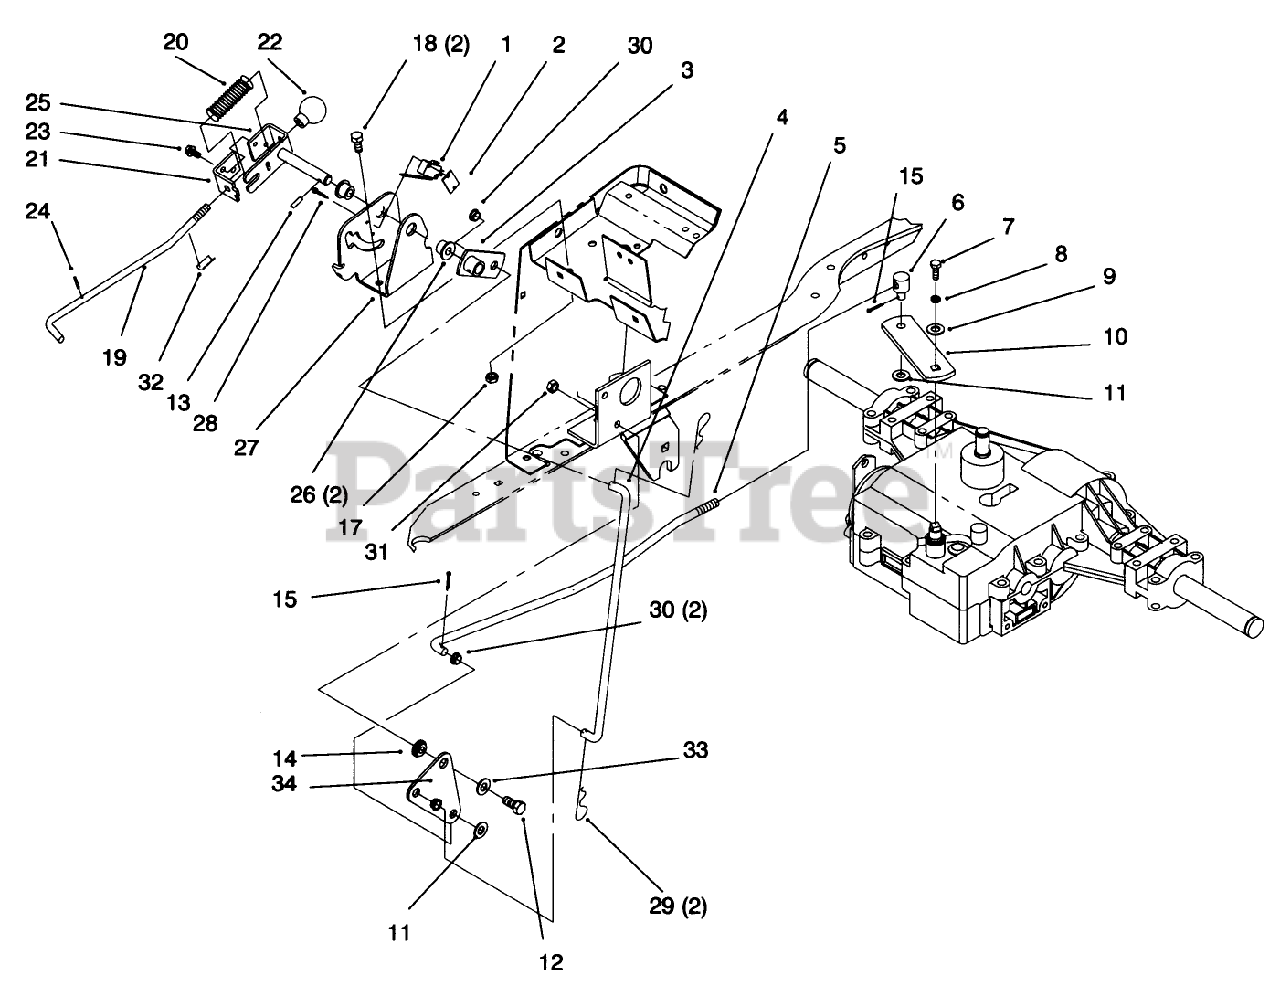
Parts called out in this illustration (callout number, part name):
1	SWITCH - CLUTCH
2	NUT-SPEED
3	TUBE-LINKAGE ASM
4	ROD - LINKAGE
5	ROD - TRANSAXLE SHIFT
7	SCREW-HH
8	WASHER-LOCK
9	SPACER
10	BRK-TRASXL SHI
11	WASHER-FLAT
12	SCREW-HH
13	PIN-ROLL, SLOTTED
14	BUSHING
15	PIN-COTTER
17	NUT-LOCK, NI
18	SCREW-HH
19	ROD - SHIFT
20	SPRING-COMPRESSION
21	BRACKET - SHAFT
23	SCREW-HWH
25	PIVOT ARM WA PLATED
26	BUSHING
27	BRKT-PIVOT MTG
31	NUT-LOCK, NI
32	DECAL - REVERSE GEAR
32	DECAL - REVERSE SHIFT
33	WASHER-FLAT
34	BRACKET - PIVOT
